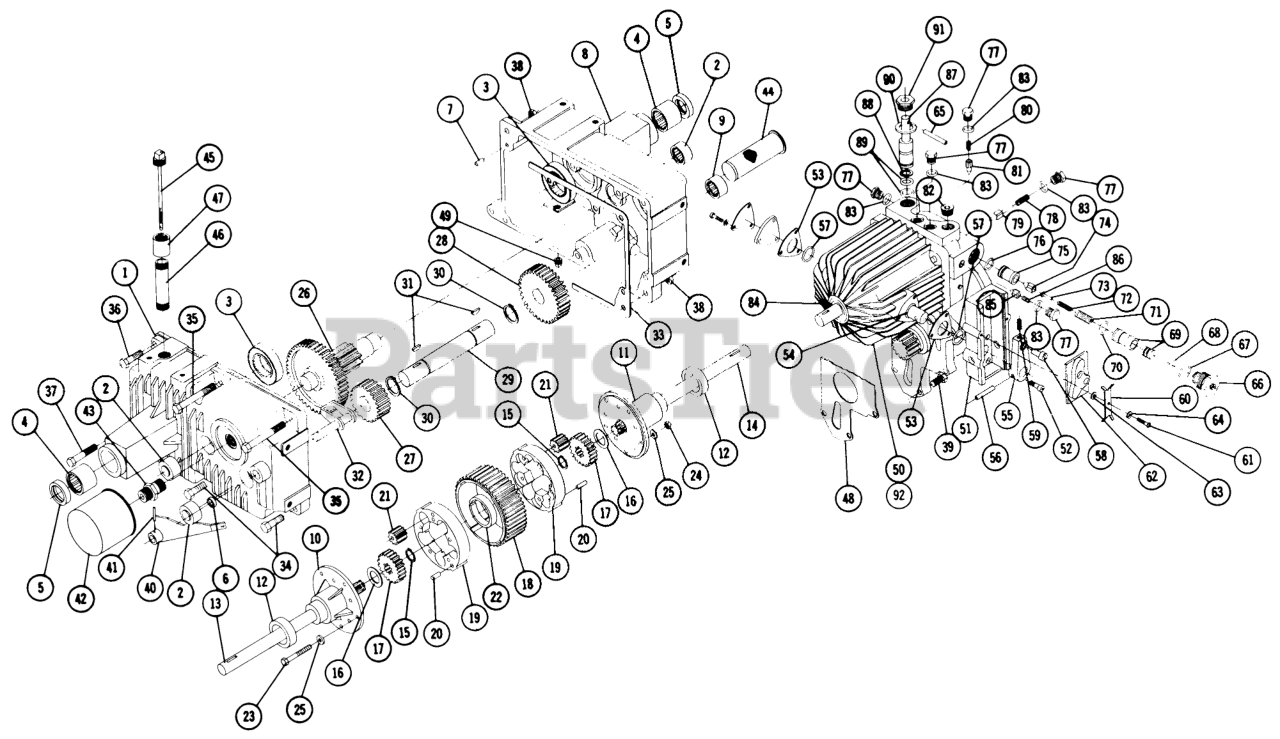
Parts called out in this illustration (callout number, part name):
2	BEARING-NEEDLE
5	SEAL-OIL
7	PIN-DOWEL
17	SIDE GEAR
19	BULLT 252
23	Bolt Hex 3 1/4
24	3/8-16 E.S.
25	Washer
31	Key
36	Bolt 3/8-16 x 2 1/4
37	Bolt Hex 3/8-16 x 1
39	Bolt, 3/8-16 x 1
43	FITTING
46	Nipple 1/2 Pipe x 31/2
47	Coupling 1/2 Pipe
50	SER BULLT 437B
55	Arm-Cam Follower
56	ROLL PIN 1/4 X 1-1/4
59	Set Screw-1/4-20 x 1/2
61	Screw #8-32 x 1/2
62	CAM
63	Washer
64	Lockwasher
65	SPIROL PIN
68	O RING
70	O RING
72	SPRING
78	SPRING-SUNDSTRAND
80	Spring Charge Pump Valve
83	O RING
92	SERV BULLT 437B
